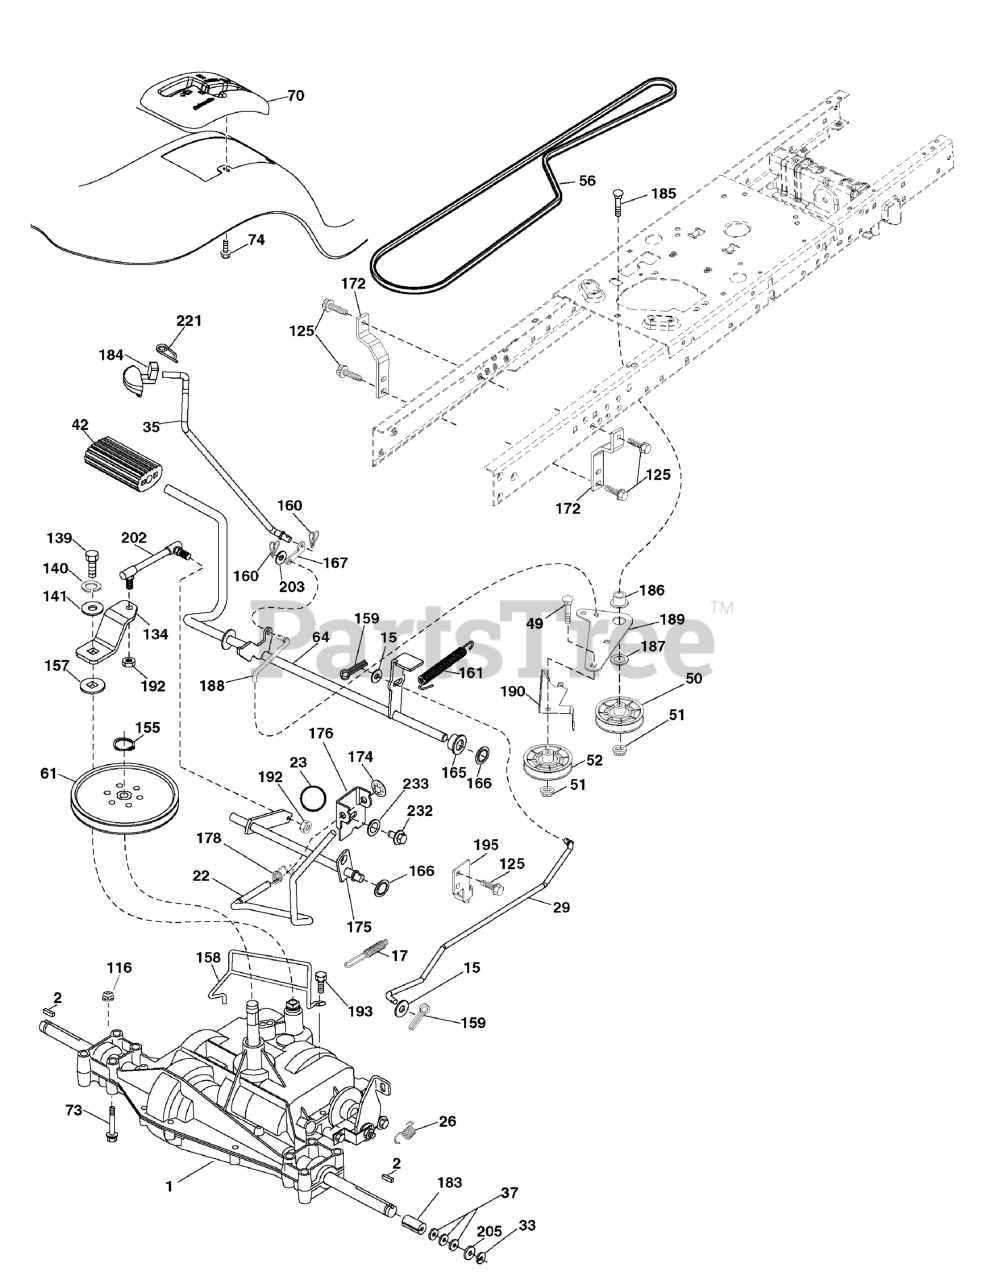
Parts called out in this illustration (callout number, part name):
2	Key Square
15	Washer 13/32 x 13/16 x 16 Ga.
17	Spring, Brake
22	Rod Shift
26	Spring Brake RTN
29	Rod, Brake
33	Ring E
35	Rod, Brake, Park
37	Washer 25/32 x 1-1/4 x 16 Ga.
42	Cover, Foot Pedal
49	Bolt
50	Pulley Idler Flat
51	Lock Nut 3/8-16
52	Idler V-Groove
56	V-Belt, Drive
61	Pulley Transaxle
64	Shaft Asm. Pedal Brake Control
70	Console
73	Bolt Hex Flghd 5/16-18 Gr. 5
74	Screw 1/4 x 1/2
116	Nut Lock Hex Flange 5/16-18
125	Screw 5/16-18 x 3/4
134	Arm Shift
139	Bolt 1/4-20 unf Gr. 8 w/Patch
140	Washer Lock Hvy Helical 1/4
141	Washer 9/32 x 3/4 x 10 Ga.
155	Ring Retainer
157	Washer Plate Shf
158	Keeper T/A
159	Pin Cotter 1/8 x 3/4
160	Retainer Clip
161	Spring, Return, Clutch
165	Busing Shaft Brake Hand Control
166	Nut Push .625
167	Latch Brake Parking
172	Strap Torque LH
174	Nut Push
175	Shaft Asm Shift
176	Arm Clevis Rod Shift
178	Spring Shift
183	Spacer Axle
184	Handle Parking Brake
185	Bolt RDHD 3/8-16 unc x 2-3/4 Gr. 5
186	Spacer Retainer
187	Washer
188	Link Clutch Ground Drive
189	Bellcrank Ground Drive
190	Keeper Bellcrank Ground Drive
192	Nut Lock Center 1/4-28
193	Screw 5/16-18 x 3/4
195	Bracket Brake Rod
202	Link Shift
203	Washer 11/32 x 11/16 x 16 Ga.
205	Washer 25/32 x 1-5/8 x 16 Ga.
221	Retainer Spring Clip Handle
232	Bolt 7/16-14 x 1 Gr.5
233	Washer Serrated
